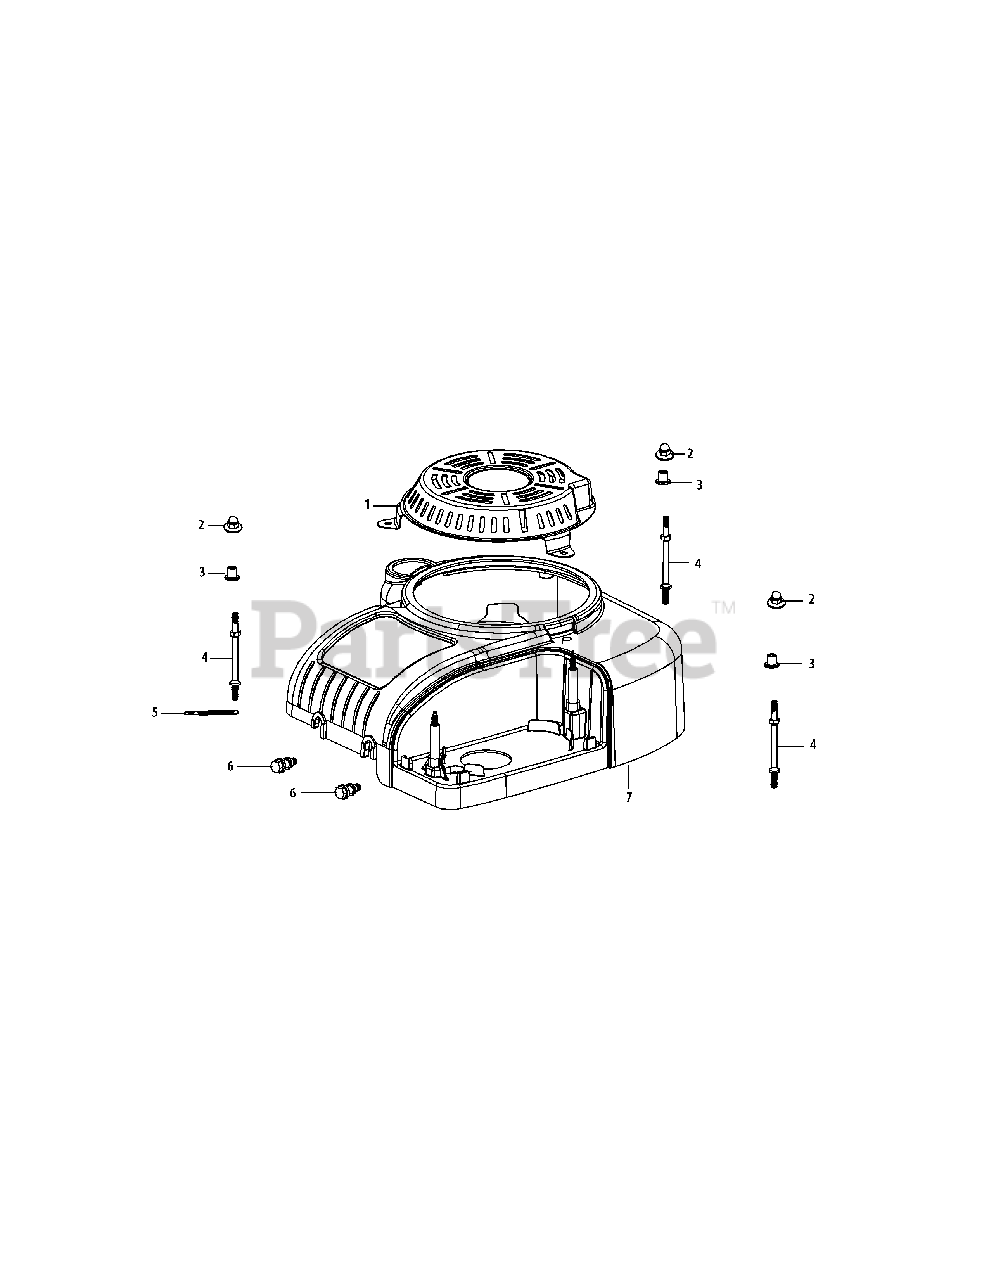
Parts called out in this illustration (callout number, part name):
1	Shroud Cover
3	Engine Shroud Spacer
4	Starter / Shroud Stud M6×100
5	Flexible Clamp
7	Engine Shroud
